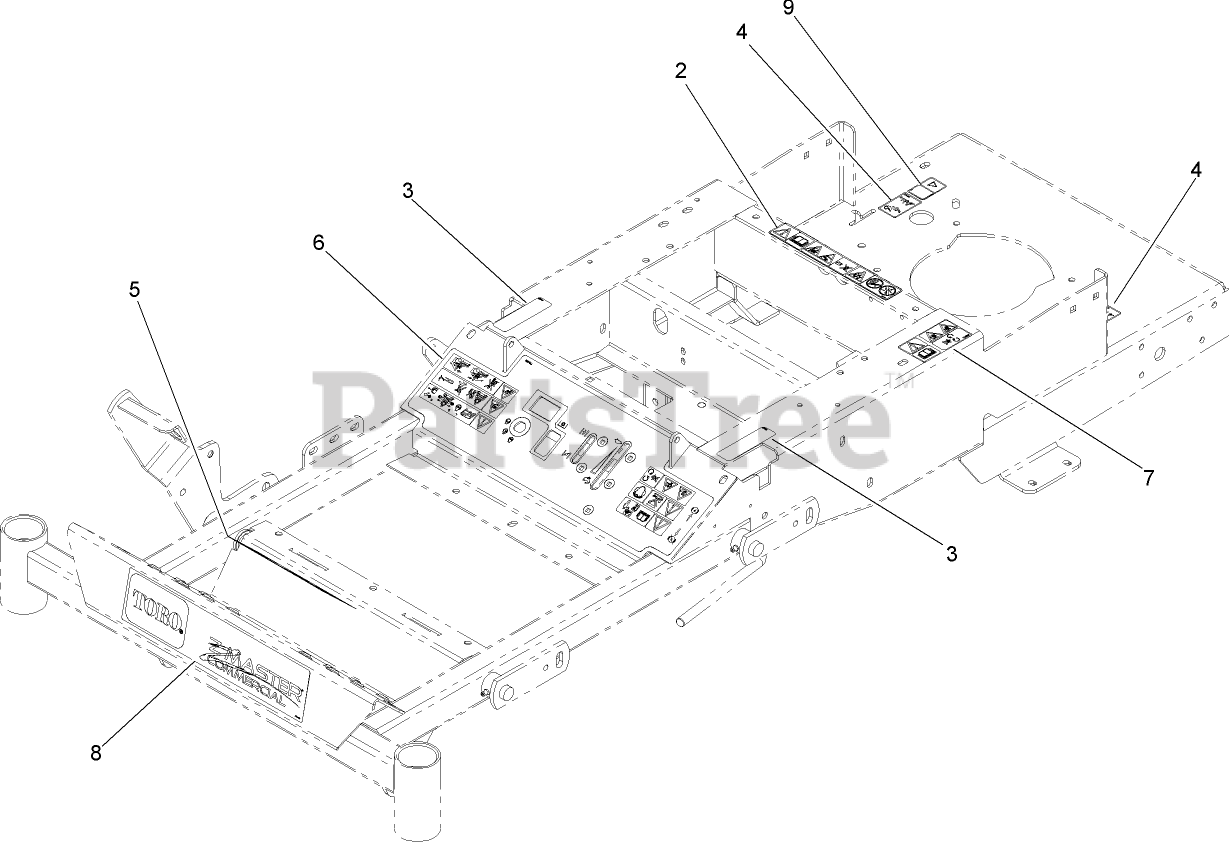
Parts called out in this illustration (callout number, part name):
2	DECAL-DANGER BATTERY, CE
3	DECAL-CONTROL, MOTION
4	DECAL-TRANSPORT, CE
5	DECAL-DANGER SLOPE, CE
6	DECAL-CONSOLE, CE
7	DECAL-DANGER, CE
9	DECAL-SURFACE, HOT
